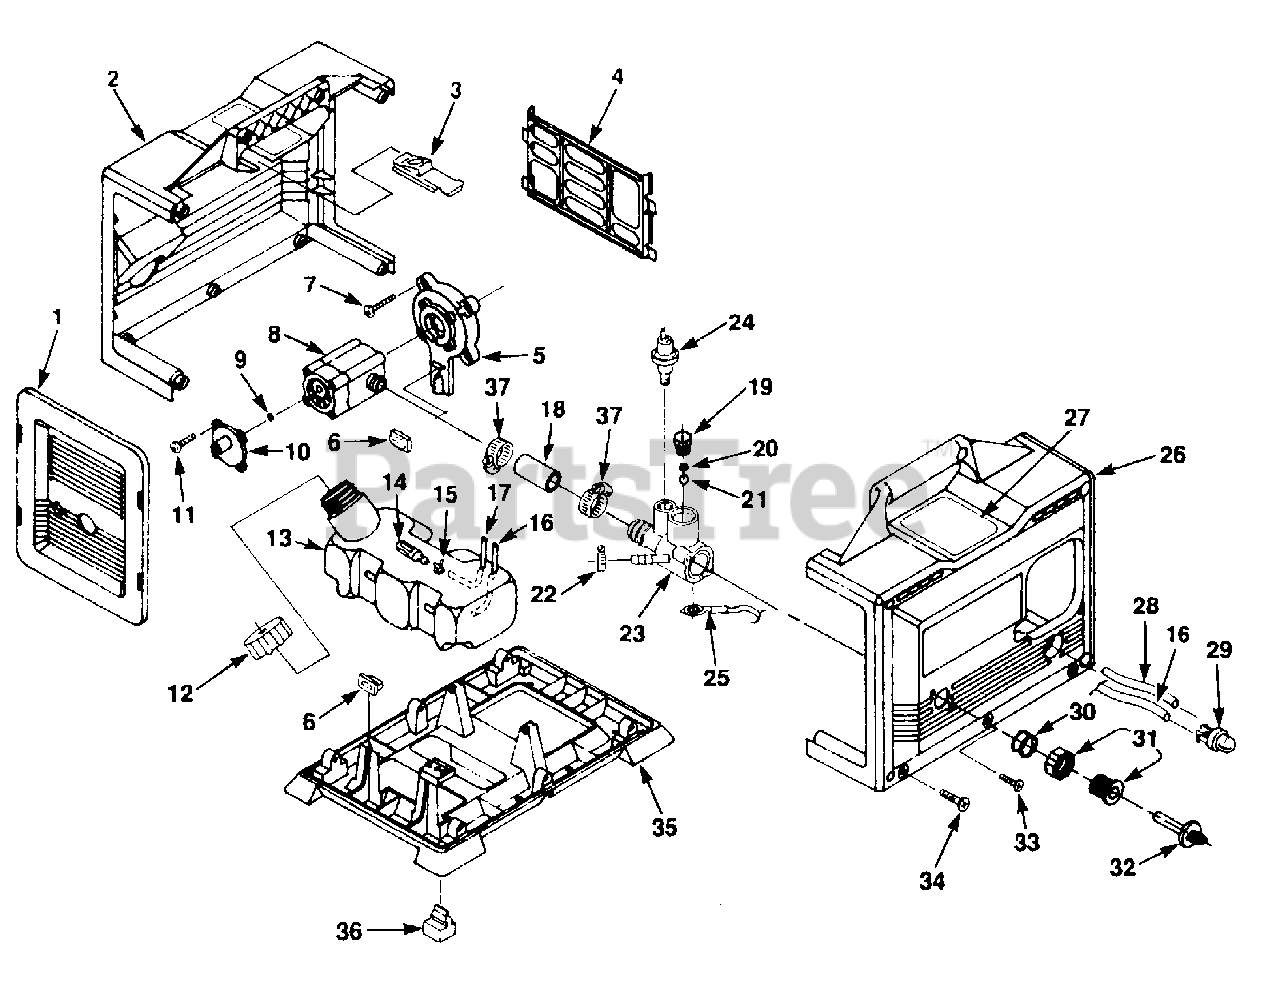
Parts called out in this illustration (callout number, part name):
1	COVER- Front
2	HOUSING- Right w/Decals
5	ADAPTOR (w/Insert & Bearing)
6	BUMPER- Rubber
7	SCREW- (10-24 X 3/4")
9	"O" RING
10	CAP- Pump
11	SCREW- Mach. Truss Hd.
12	CAP- Fuel Tank
13	FUEL TANK ASSEMBLY
14	FILTER- Fuel
15	CLAMP- Wire
16	TUBING- Rubber (11")
17	TUBING- Rubber (8")
18	HOSE- Rubber
19	PLUG- Vent
20	"O" RING
21	BALL-Plastic
22	CLAMP- Hose (#4)
23	MANIFOLD- Plumbing
24	SWITCH- Pressure
25	LEAD- Ground
26	HOUSING- Left (w/Decal)
27	DECAL- Warning
28	TUBING- Rubber (6")
29	BULB Primer
30	SPRING & ADAPTOR
31	ADAPTOR- Garden Hose
32	FILTER- Inlet
33	SCREW- Thd. Form (10-24 x 3/4")
34	SCREW- Thd. Form (10-14 x 3/4")
36	FOOT- Rubber
37	CLAMP- Hose (#6)
